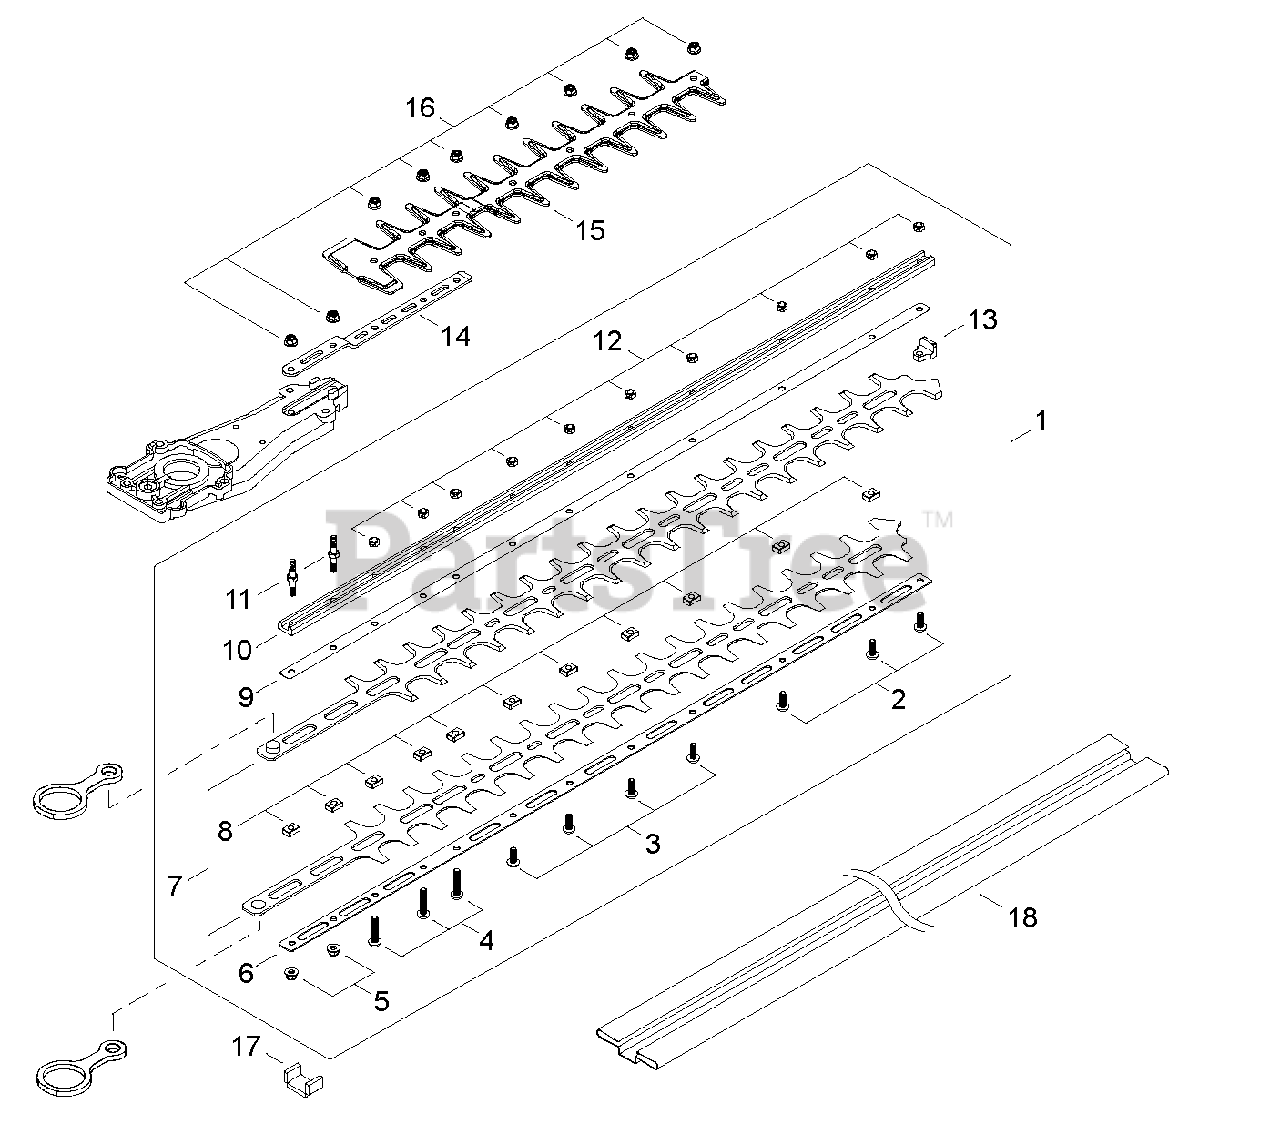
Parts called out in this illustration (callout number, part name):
1	BLADE KIT - 30" (76cm)
2	SCREW - 5X14
3	SCREW - 5X22
4	SCREW - 5X25
5	NUT - 5
6	PLATE - LOWER
7	BLADE - 30" (76cm)
8	SPACER
9	PLATE, UPPER
10	SUPPORT, BLADE - 30" (76cm)
11	STUD - 5
12	LOCKNUT - 5
13	BLOCK
14	BRACKET, CUTTER
15	SHIELD, BLADE
16	NUT - 5
17	SEAL, FELT
18	COVER, BLADE - 30" (76cm)
